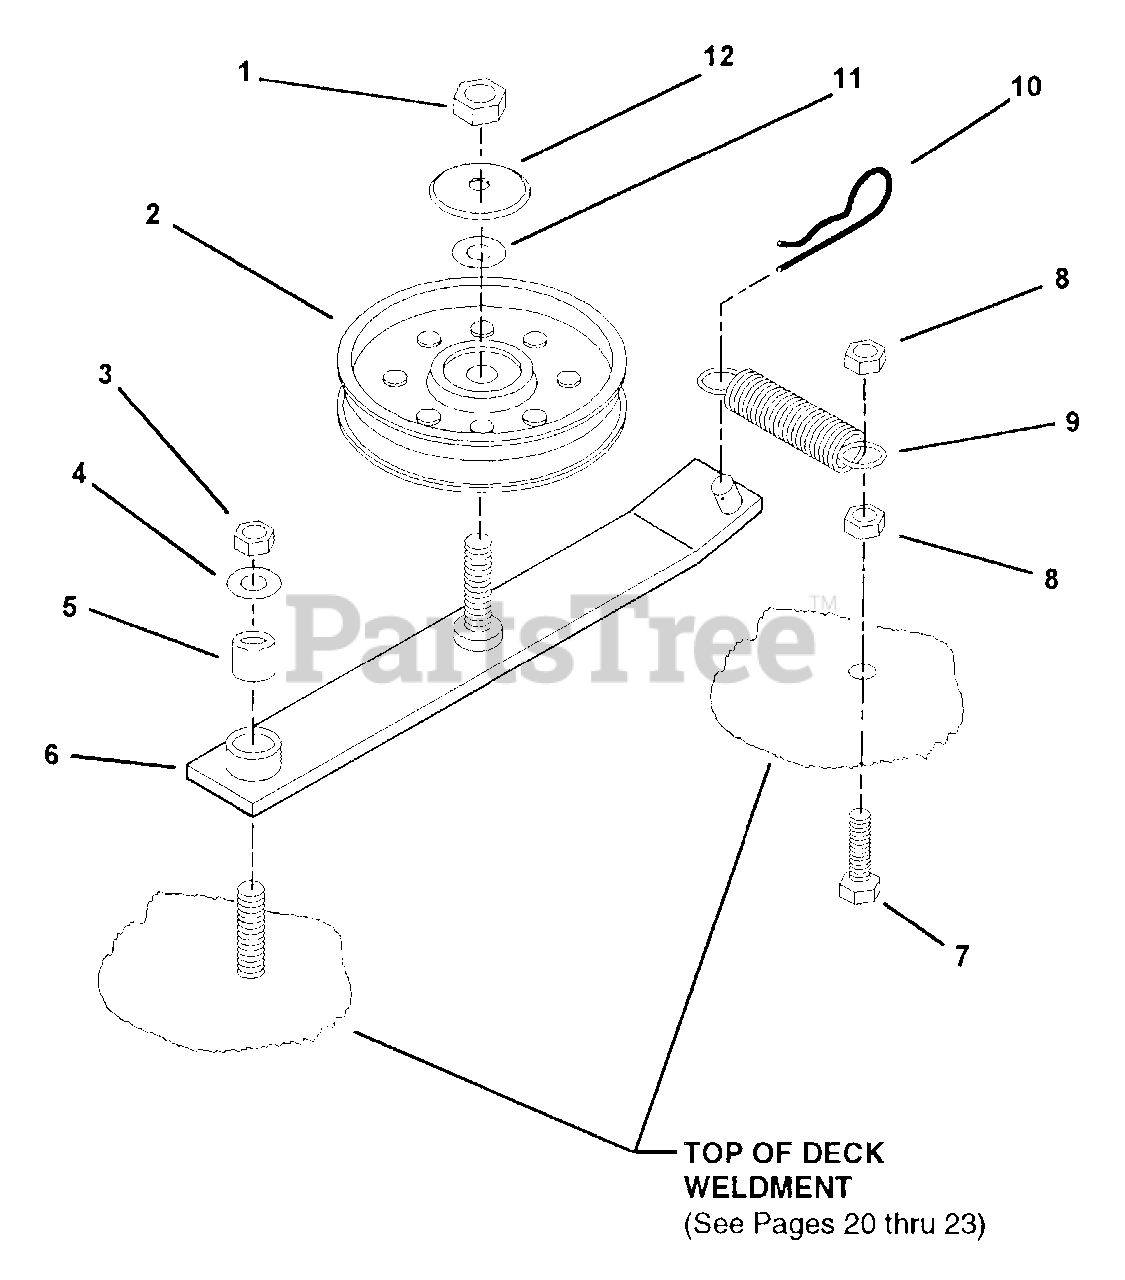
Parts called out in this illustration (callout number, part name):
1	NUT, HEX. 1/2-13 NYLOC
2	PULLEY, FLAT IDLER, 1/2 BORE, 4" O.D.
3	NUT, HEX. 3/8-16 NYLOC
4	WASHER, FLAT STD. 3/8" W SERIES
5	BEARING OILITE, 3/8 I.D. X 5/8" O.D.
6	SINGLE IDLER ARM WELDMENT, 60" DECK
7	BOLT, 3/8-24 X 1-1/4" GR. 5
8	NUT, 3/8-24, M-F LOCKNUT
9	SPRING, EXTENSION, 3/4 X 4" O.A.L.
10	PIN, HAIRSPRING, 1/8 X 2-1/2"
11	1/2" WASHER,TYPE B NARROW
12	WASHER, BEARING CAP
